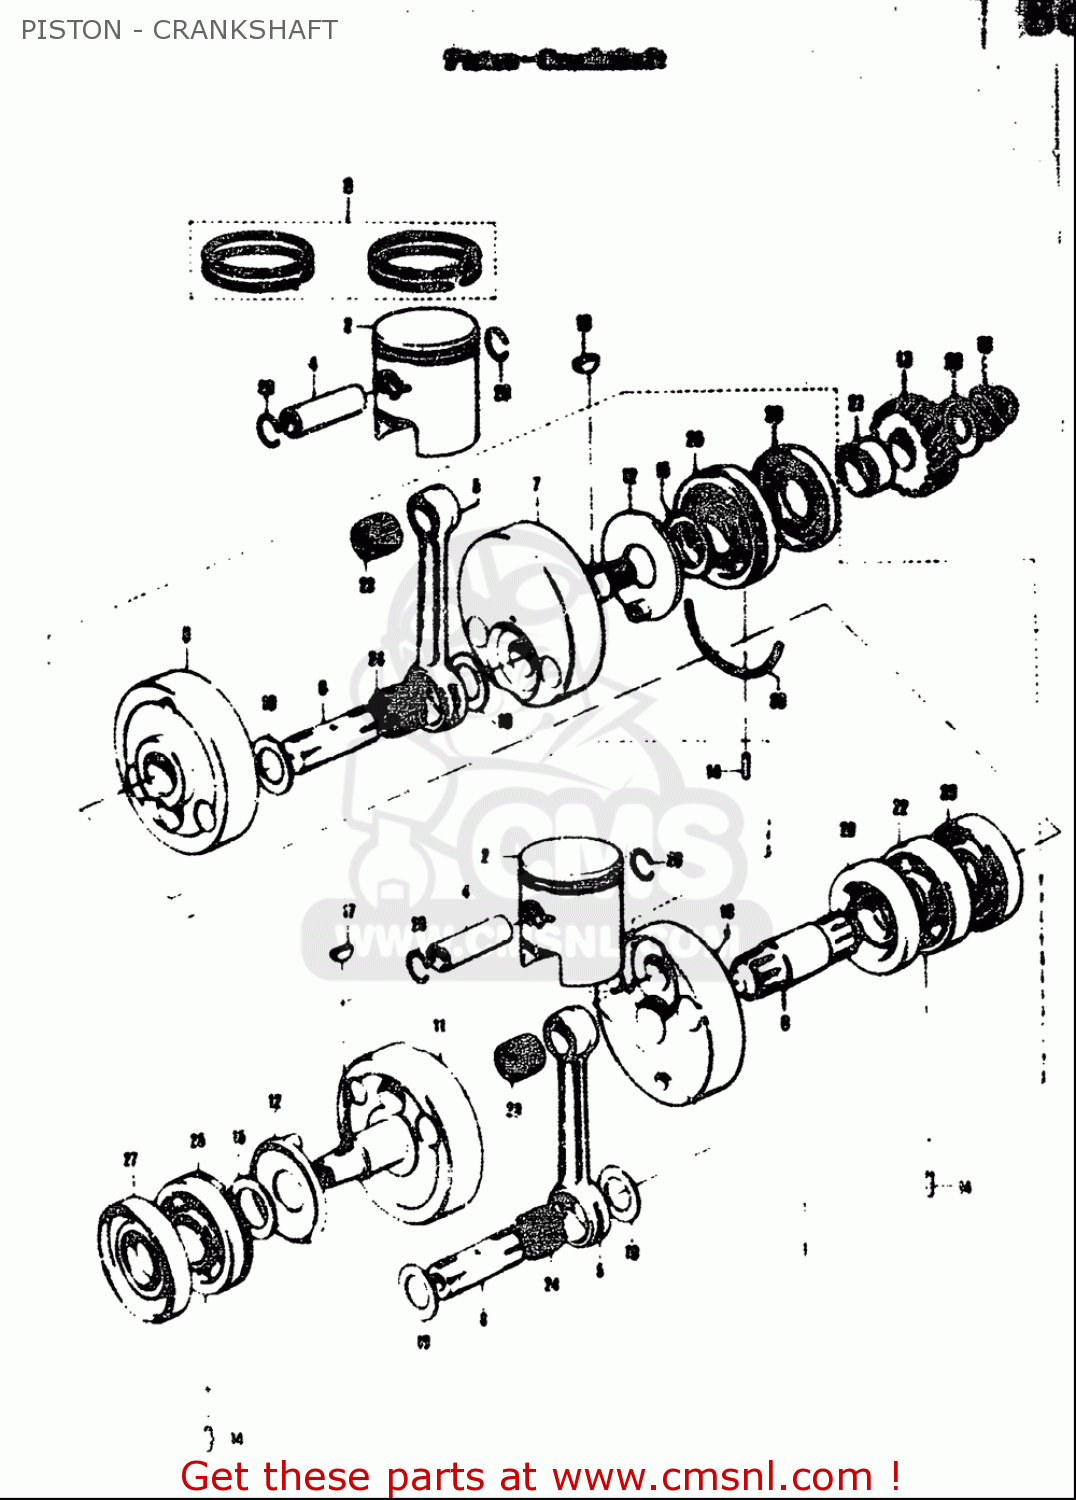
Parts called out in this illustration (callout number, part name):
4	PIN,PISTON
15	SHIM(25X40X1)
16	KEY
17	KEY
19	WASHER (20X34X1)
20	WASHER
23	BEARING(16X21X19.6)
24	BEARING(20X26X16.7)
25	BEARING(25X65X17)
27	SEAL,OIL(25X65X12)
28	SEAL,OIL
29	RING,SNAP 16MM
